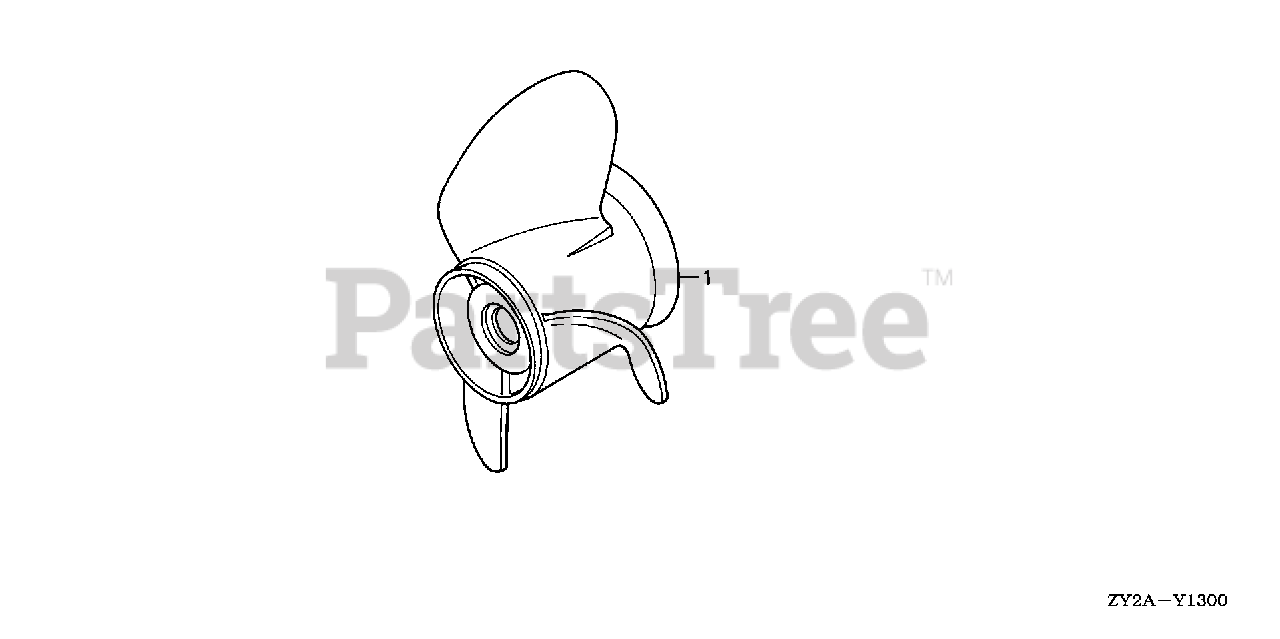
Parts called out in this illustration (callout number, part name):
1	PROPELLER, THREE-BLADE (14-1/2X15) (C/R)
1	PROPELLER, THREE-BLADE (14-1/4X17) (C/R)
1	PROPELLER, THREE-BLADE (14X19) (C/R)
1	PROPELLER, THREE-BLADE (14X21) (C/R)
1	PROPELLER, THREE-BLADE (14-1/2X23) (C/R)
